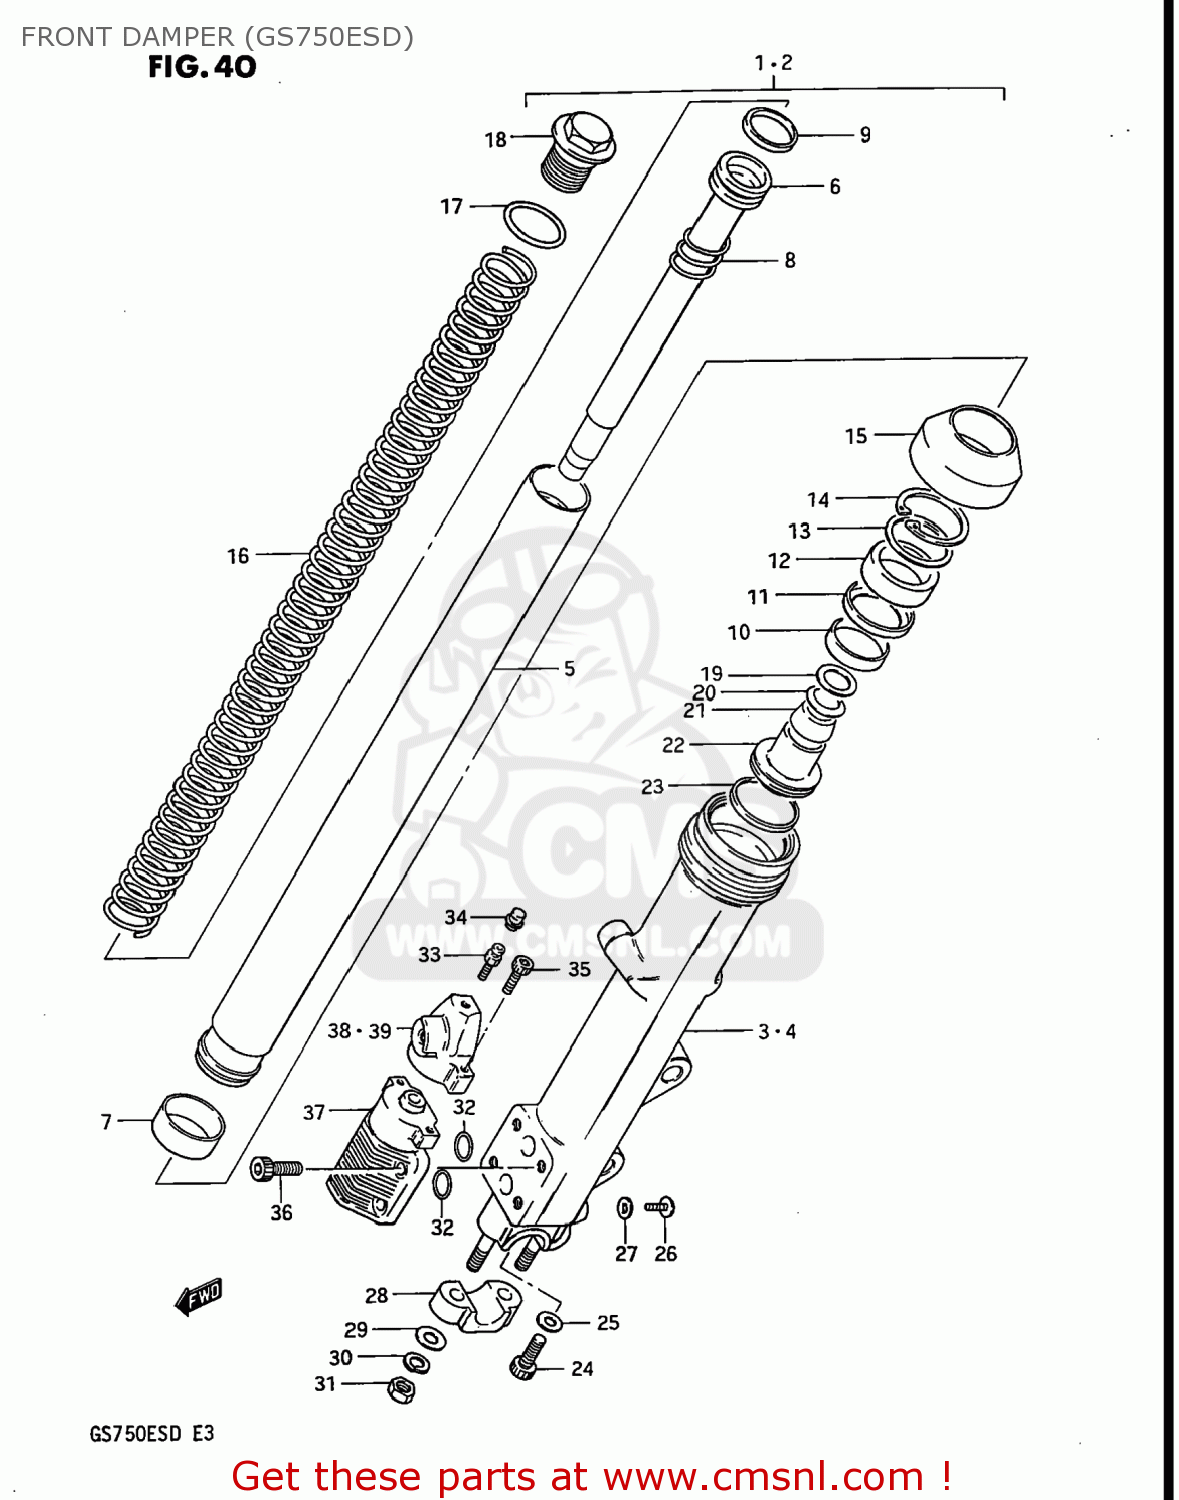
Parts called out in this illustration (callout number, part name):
1	DAMPER ASSEMBLY,RIGHT
2	DAMPER ASSEMBLY,LEFT
3	TUBE,OUTER,RIGHT
4	TUBE,OUTER,LEFT
5	TUBE,INNER
6	CYLINDER,FRONT FORK
7	PISTON
8	SPRING,FORK REBOUND
9	RING,PISTON
10	BUSHING,GUIDE
11	SPACER,SEAL
12	OIL SEAL,FRONT FORK
13	RING,BACKUP
14	CIRCLIP,INNTERNAL
15	BOOT
16	SPRING
17	O RING
18	CAP,FORK INNER TUBE
19	VALVE
20	SPRING,VALVE
21	VALVE,OIL LOCK PIEACE
22	PIECE,OIL LOCK
23	RING,PISTON
24	BOLT(8X27)
25	GASKET (NAS)
26	SCREW 4X6
27	GASKET (NAS)
28	HOLDER,AXLE
29	WASHER
30	LOCK WASHER
31	NUT
32	O RING,FR FORK
33	BREATHER
34	CAP
35	BOLT
36	BOLT
37	VALVE SET,MODULATOR
38	PLUNGER SET,MODULATOR,RIGHT
39	PLUNGER SET,MODULATOR,LEFT
